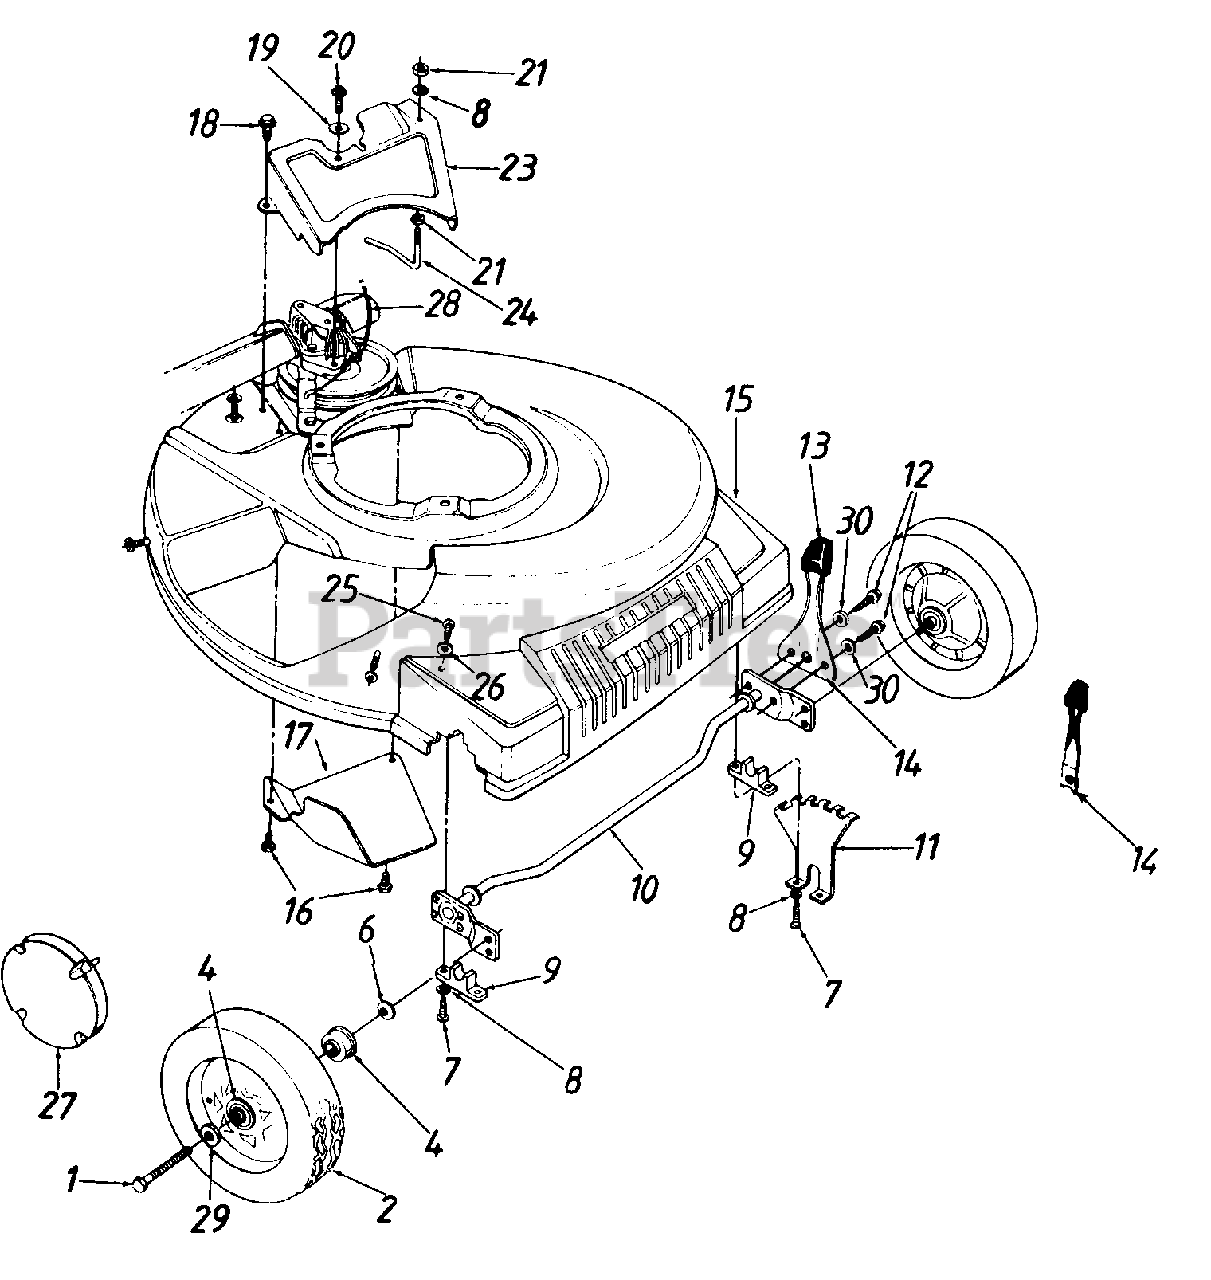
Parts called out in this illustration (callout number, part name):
1	Front Axle Bolt
2	Wheel Ass'y. Comp. 8 x 2"
4	Flange Ball Brg. .501" I.D.
6	Bell-Wash. .380" I.D. x .88
7	Hex Wash. Hd. B-Tap Scr. 1/4-20
8	L-Wash. 1/4" I.D.
9	Block Bushing
10	Axle Ass'y.
12	Hex Wash. Hd. TT-Tap Scr. 1/4-20 x .5" Lg.
13	Knob
14	Spring Lever (With 1 hole)
15	Plastic Front End
16	Hex B-Tap Scr. 1/4" x .38"
19	Bell-Wash. .265" I.D. x .75"
20	Hex Wash. Hd. B-Tap Scr. 1/4 x .62"
21	Hex Nut 1/4-20 Thd.
25	Truss B-Tap Scr. 5/16 x .75"
26	Bell-Wash. .345" I.D. x .88" O.D.
27	Hub Cap
28	S.P. Cable 50" Lg.
29	Wave Wash. .53" I.D. x .78" O.D.
30	External L-Wash. 1/4" I.D.
